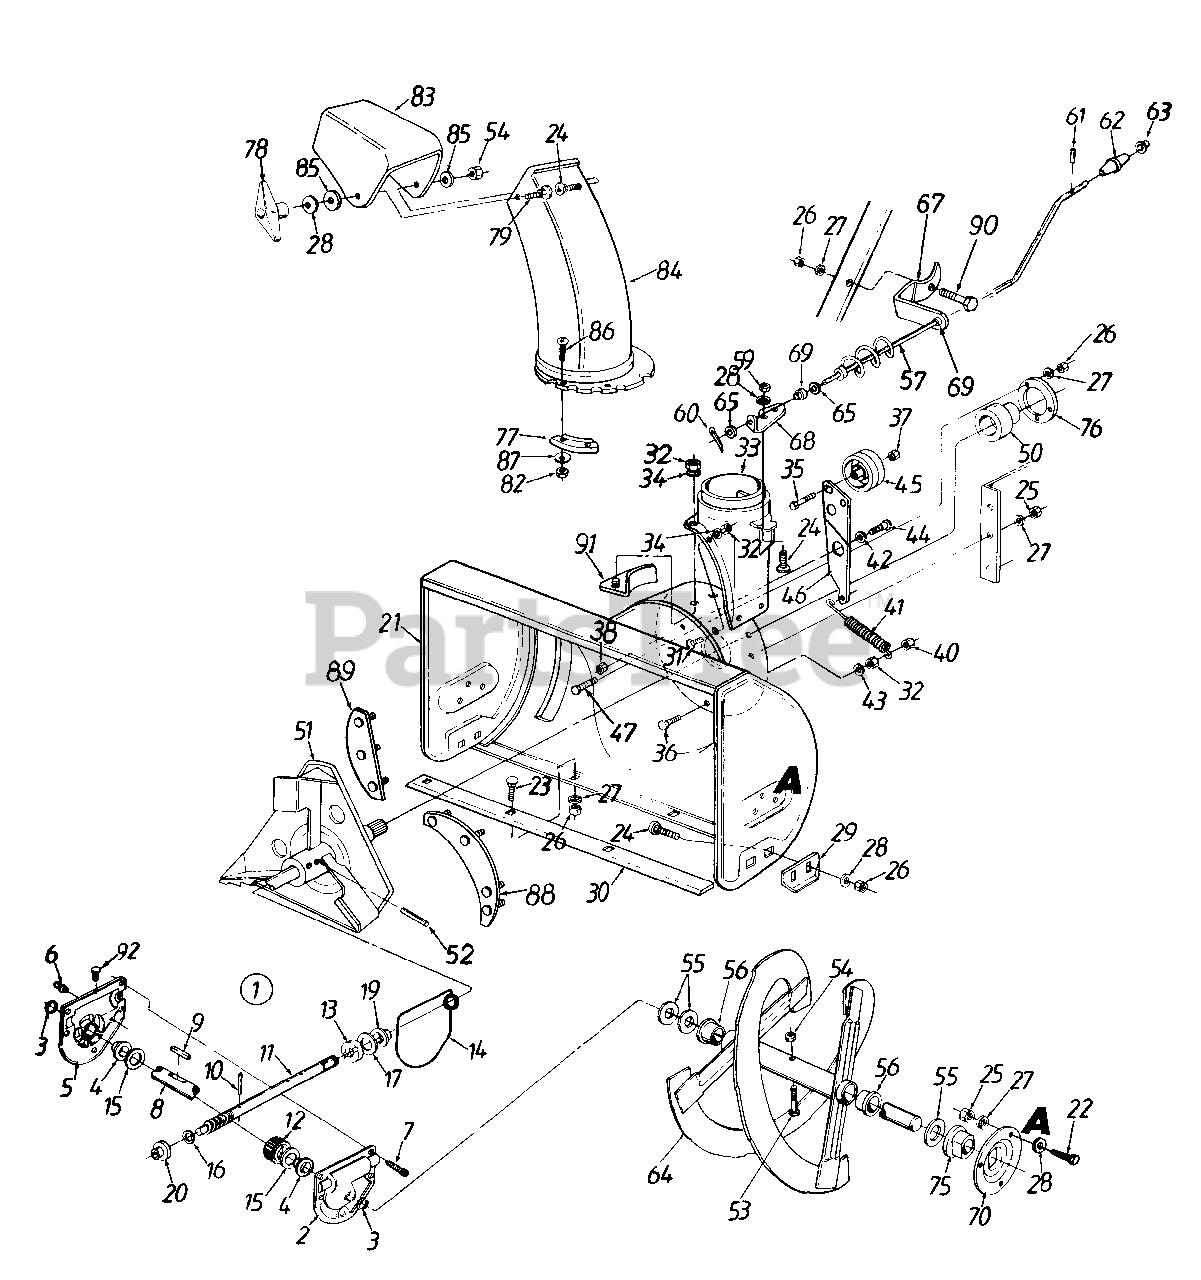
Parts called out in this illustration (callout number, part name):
1	Auger Gear Box Ass'y. Comp.
2	Reducer Housing - L.H.
3	Oil Seal
4	Flange Bearing .75" I.D.
5	Reducer Housing - R.H.
6	Grease Fltting
7	Hex TT-Tap Scr. 1/4-20 x .75" Lg.
8	24" Auger Shaft
9	#61 Hi-Pro Key 3/16" x 5/8" Dia.
10	Spiral Pin 1.25" Lg.
11	Impeller Shaft
12	Worm Gear
13	Thrust Collar
14	"O"-Ring (Special)
15	Fl-Wash .76" I.D. x 1.5" O.D.
16	Fl-Wash .5" I.D. x 1" O.D.
17	Fl-Wash .76" I.D. x 1.49" O.D.
19	Flange Bearing .75" I.D.
20	Flange Bearing .503" I.D.
21	24" Auger Housing Ass'y.
22	Hex Bolt 5/16-24 x .75" Lg.
23	Carriage Bolt 5/16-18 x .62" Lg.
24	Carriage Bolt 5/16-18 x .75" Lg.
25	Hex Nut 5/16-24 Thd.
26	Hex Nut 5/16-18 Thd.
27	L-Wash. 5/16" I.D.
28	Bell-Wash .345" I.D. x .88" O.D.
30	24" Shave Plate
31	Truss Mach. Scr. 1/4-20 x .5" Lg.
32	Hex Nut 1/4-20 Thd.
33	Chute Adapter
34	Spring Washer 1/4" I.D.
35	Hex Bolt 3/8-24 x 1.5" Lg. (Gr. 5)
36	Hex Bolt 1/4-20 x .75" Lg. (Gr. 5)
37	Hex ins. L-Nut 3/8-24 Thd.
38	Hex Top L-Nut 3/8-16 Thd.
40	Hex L-Nut 1/4-20 Thd.
41	Ext. Spring 3.6" Lg.
42	Fl-Wash. 5/8" I.D. x 1.25"
43	L-Wash 1/4" I.D.
44	Shld. Bolt .625" Dia x .170" Lg.
45	Fl-Idler 2.75" O.D.
47	Hex Bolt 5/16-18 x 5/8" Lg
50	Ball Bearing .75" I.D.
52	Spiral Pin 1.5" Lg
53	Shear Bolt 5/16-18 x 1 5" Lg.
54	Hex Cent L-Nut 5/16-18 Thd.
55	Fl-Wash. 76" I.D. x 1 49"
56	Flange Bushing .8" I.D
57	Chute Crank Ass'y
59	Hex Ins. L-Nut 5/16-18 Thd
60	Cotter Pin 3/32" Dia. x 75"
61	Roll Pin 1/8" Dia. x 63" Lg
62	Chute Crank Knob
63	Push Nut
65	Fl-Wash. 385" I.D x .62" O.D.
69	Plastic Bushing .38" I.D.
75	Plastic Bearing w/Flats
76	Bearing Housing
77	Chute Flange Keeper
78	Knob
79	Carriage Bolt 5/16-18 x 1" Lg.
82	Hex L-Nut 1/4-20 Thd.
83	Upper Chute
84	Lower Chute
85	Fl-Wash. 344" I.D x 1.125"
86	Truss Mach. Scr. 1/4-20 x .75" Lg.
87	Fl-Wash. 1/4" I.D.
91	Chute Reinforcement
